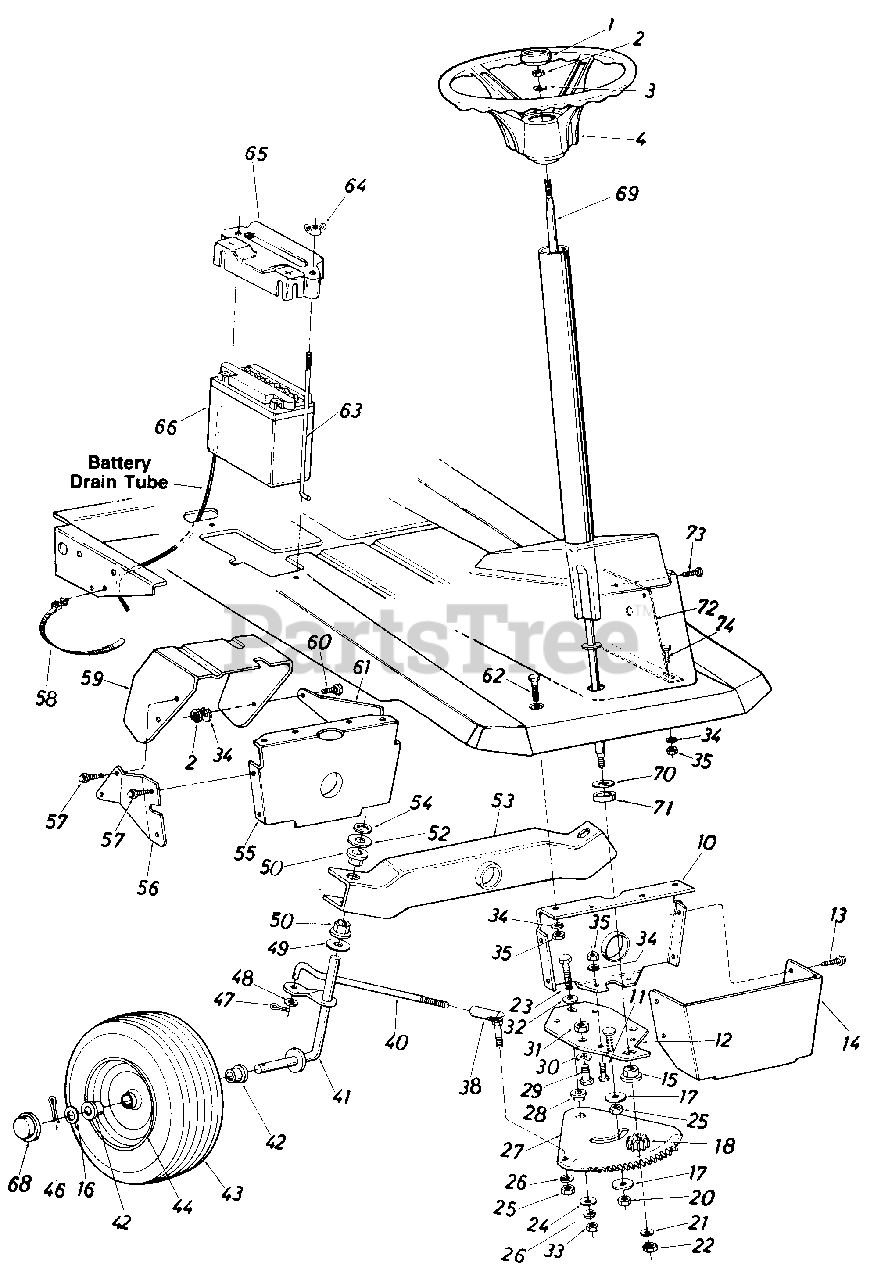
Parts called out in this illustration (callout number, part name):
1	Steering Wheel Cap
2	Hex Nut 5/16-24 Thd.
3	Bell-Wash. .345" I.D. x .88" O.D.
4	Steering Wheel Ass'y.
10	Pivot Bar Bracket
11	Hex Bolt 5/16-18 x .75" Lg.
12	Steering Gear Support Brkt.
13	Hex Wash. Hd. AB-Tap Scr. 1/4 X .62" Lg .
17	Fl-Washer 3/8" I.D. x 1.37 O.D.
18	Steering Pinion Gear
20	Hex L-Nut 3/8-24
21	Fl-Wash. .34" I.D. x .68" O.D.
22	Hex Nut 5/16-24 Thd.
23	Hex Bolt 3/8-24 x 1.25" Lg. (Grade 5)
24	Fl-Wash. .385" I.D. x 1.38"
25	Hex Nut 3/8-24 Thd.
26	L-Wash. 3/8" I.D.
27	Steering Gear Segment
28	Shoulder Spacer .622" Dia. x .218
29	Hex Bolt
30	Fl-Wash. .530" I.D. x .930"
31	Hex Nut 1/2-13 Thd.
32	Bell-Wash. .385" I.D. x .88"
33	Hex Nut 3/8-24 Thd.
34	L-Wash. 5/16" I.D.
35	Hex Nut 5/16-18 Thd.
38	Ball Joint Ass'y. 3/8-24 Thd.
40	Steering Tie Rod
41	Front Axle Ass'y. R.H.
42	Flange Bearing .632" I.D.
43	Front Wheel Ass'y. Comp.
44	Front Wheel Rim Only
46	Cotter Pin 1/8" Dia. x 1.25"
47	Cotter Pin 1/8" Dia. x 1.00
48	Fl-Wash. .385" I.D. x .87"
49	Fl-Wash. .635" I.D. x 1.12"
50	Hex Flange Bearing
52	Fl-Wash. .635" I.D. x 1.12"
53	Pivot Bar Ass'y.
54	Speed Nut 5/8" I.D.
55	Pivot Bar Bracket
56	Bracket Reinforcement R.H.
57	Hex Wash. Hd. AB-Tap Scr. 1/4 X .62" Lg.
58	Cable Tie
59	Clutch-Brake Pedal Ass'y.
60	Hex Bolt 5/16-18 x .75" Lg.
61	Bracket Reinforcement L.H.
62	Hex Bolt 5/16-18 x .75" Lg.
63	Battery Hold Down Rod
64	Wing Nut Solid 1/4-20 Thd.
65	Battery Hold Down Cover
66	12V Battery
68	Hub Cap
69	Steering Shaft Ass'y.
70	Fl-Wash. .62" I.D. x 1.25" O.D.
71	Spacer (Plastic)
74	Hex Bolt 5/16-18 x 2.00" Lg.
